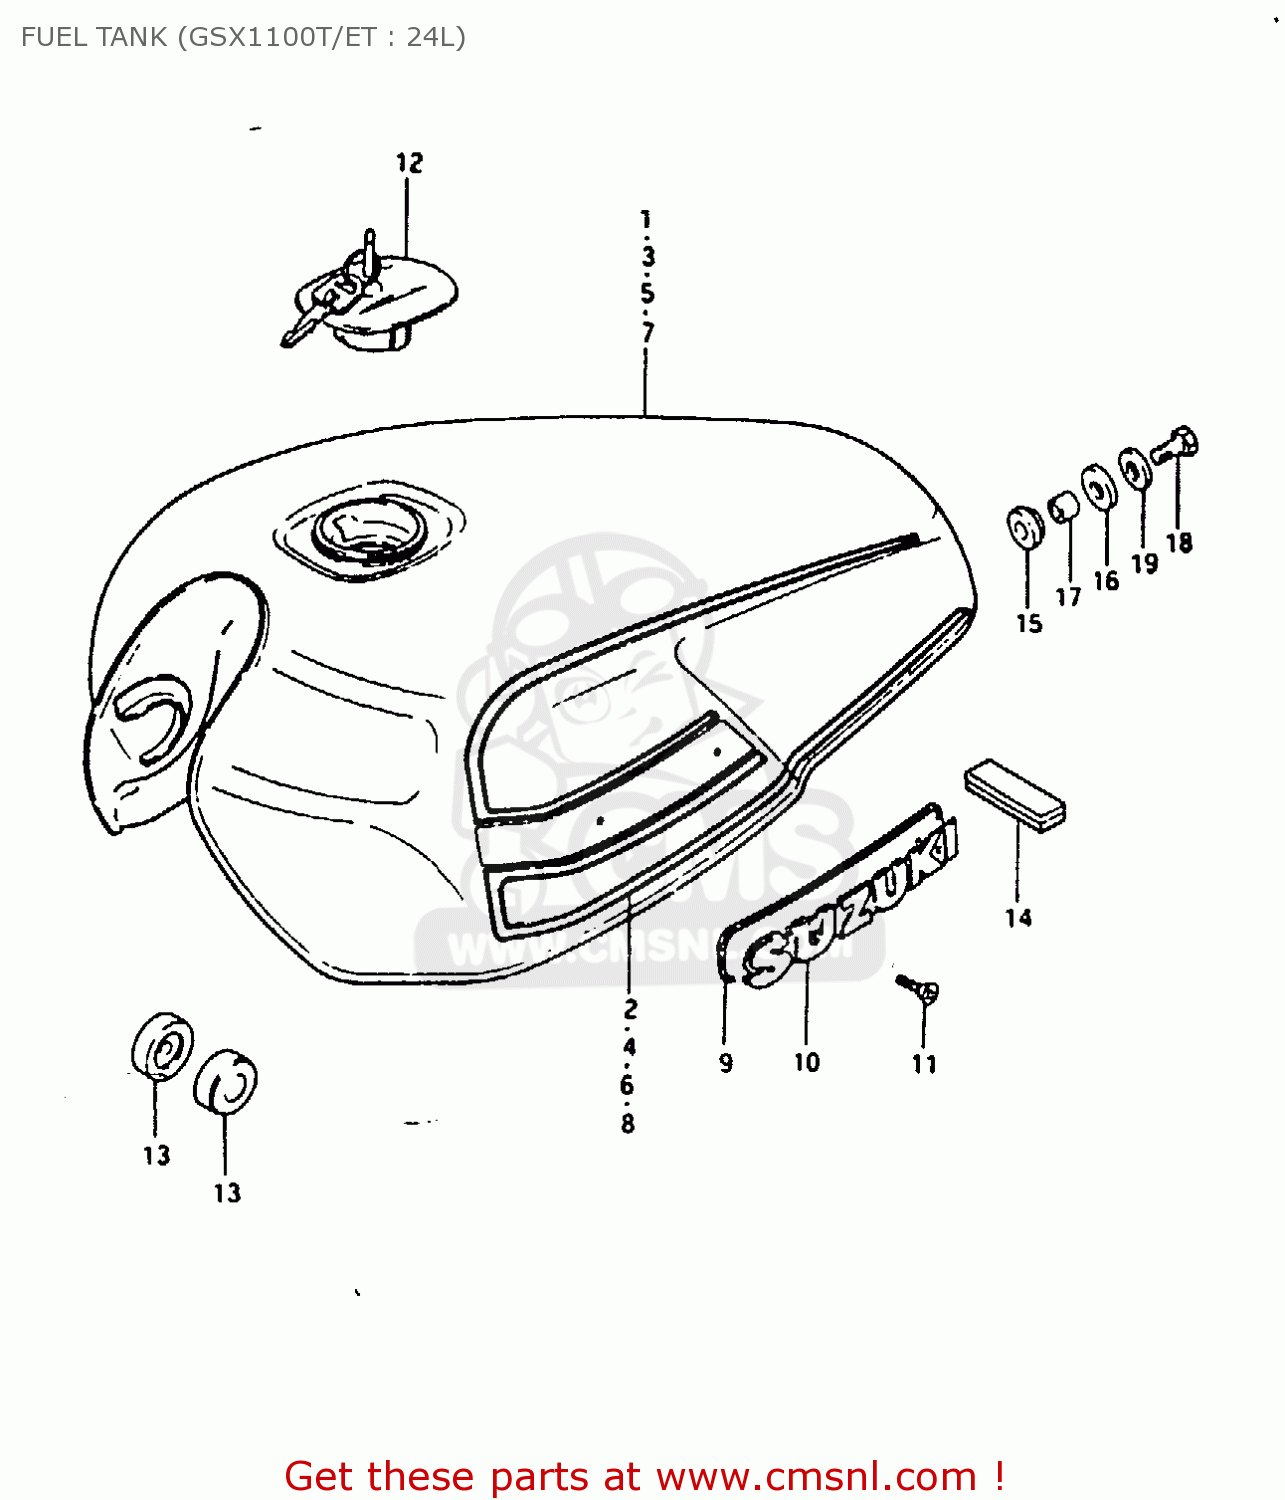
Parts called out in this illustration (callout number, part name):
1	TANK, FUEL (BLACK)
2	TAPE SET
3	TANK, FUEL (SILVER)
4	TAPE SET
5	TANK, FUEL (RED)
6	TAPE SET
7	TANK, FUEL (BLUE)
8	TAPE SET
10	EMBLEM,FUEL TANK
11	SCREW 3X6
12	CAP SET,FUEL TANK
13	CUSHION
14	CUSHION
15	CUSHION
16	CUSHION
17	SPACER(8.5X12X19)
18	BOLT (8X30)
19	WASHER (8.5X29X1.6)
